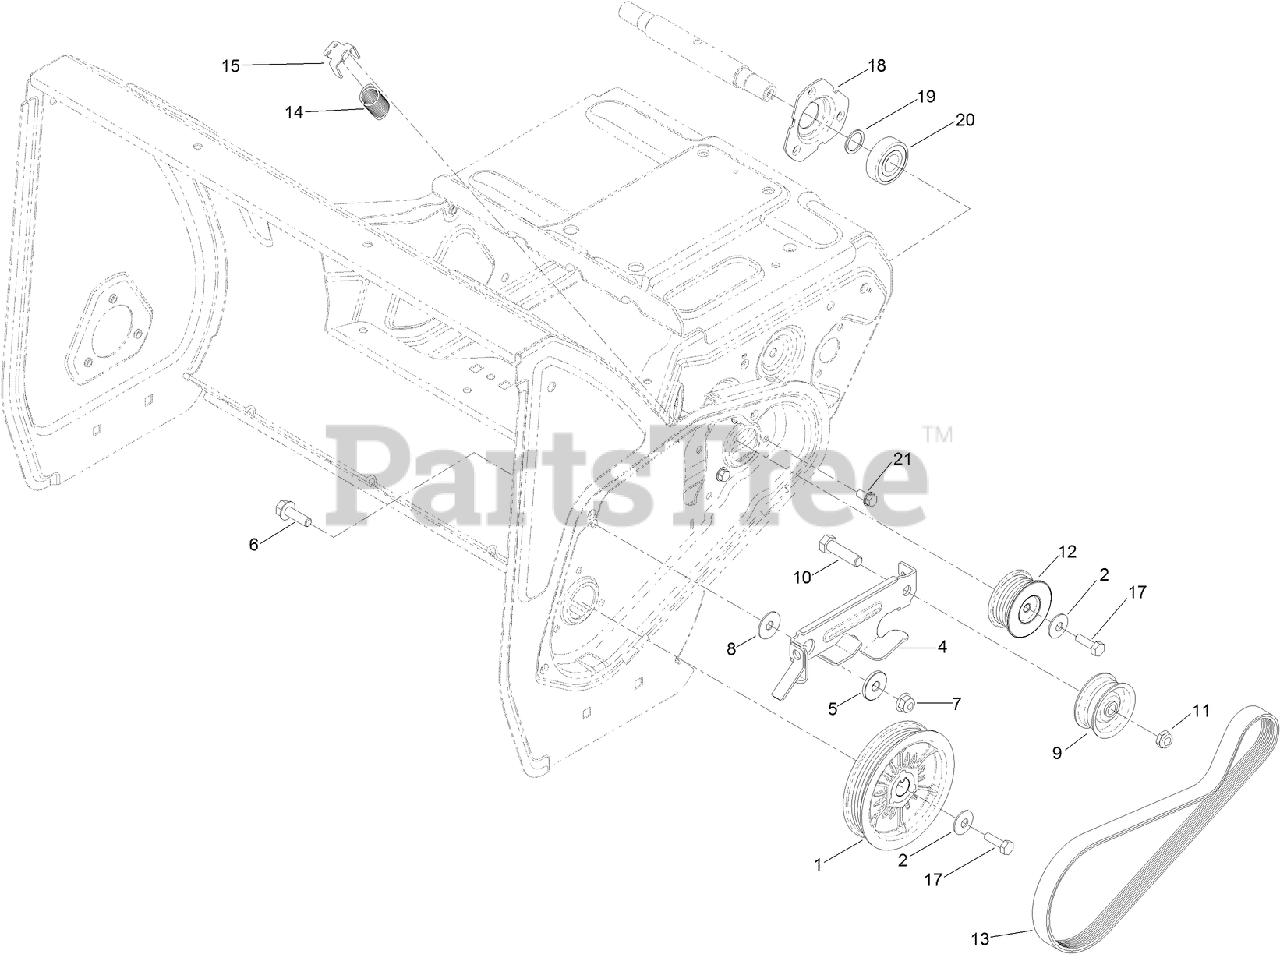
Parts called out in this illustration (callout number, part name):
1	PULLEY-ROTOR
2	WASHER-BELLEVILLE
5	BUSHING-IDLER
6	SCREW-HHF
7	NUT-HF, NI
8	WASHER
9	PULLEY-IDLER, FLAT
10	SCREW-HH
12	PULLEY-JACKSHAFT, ROTOR
13	BELT-POLY V
14	SPRING-EXTENSION
17	SCREW-HH
19	WASHER-THRUST
20	BEARING-BALL
21	SCREW-HWH
